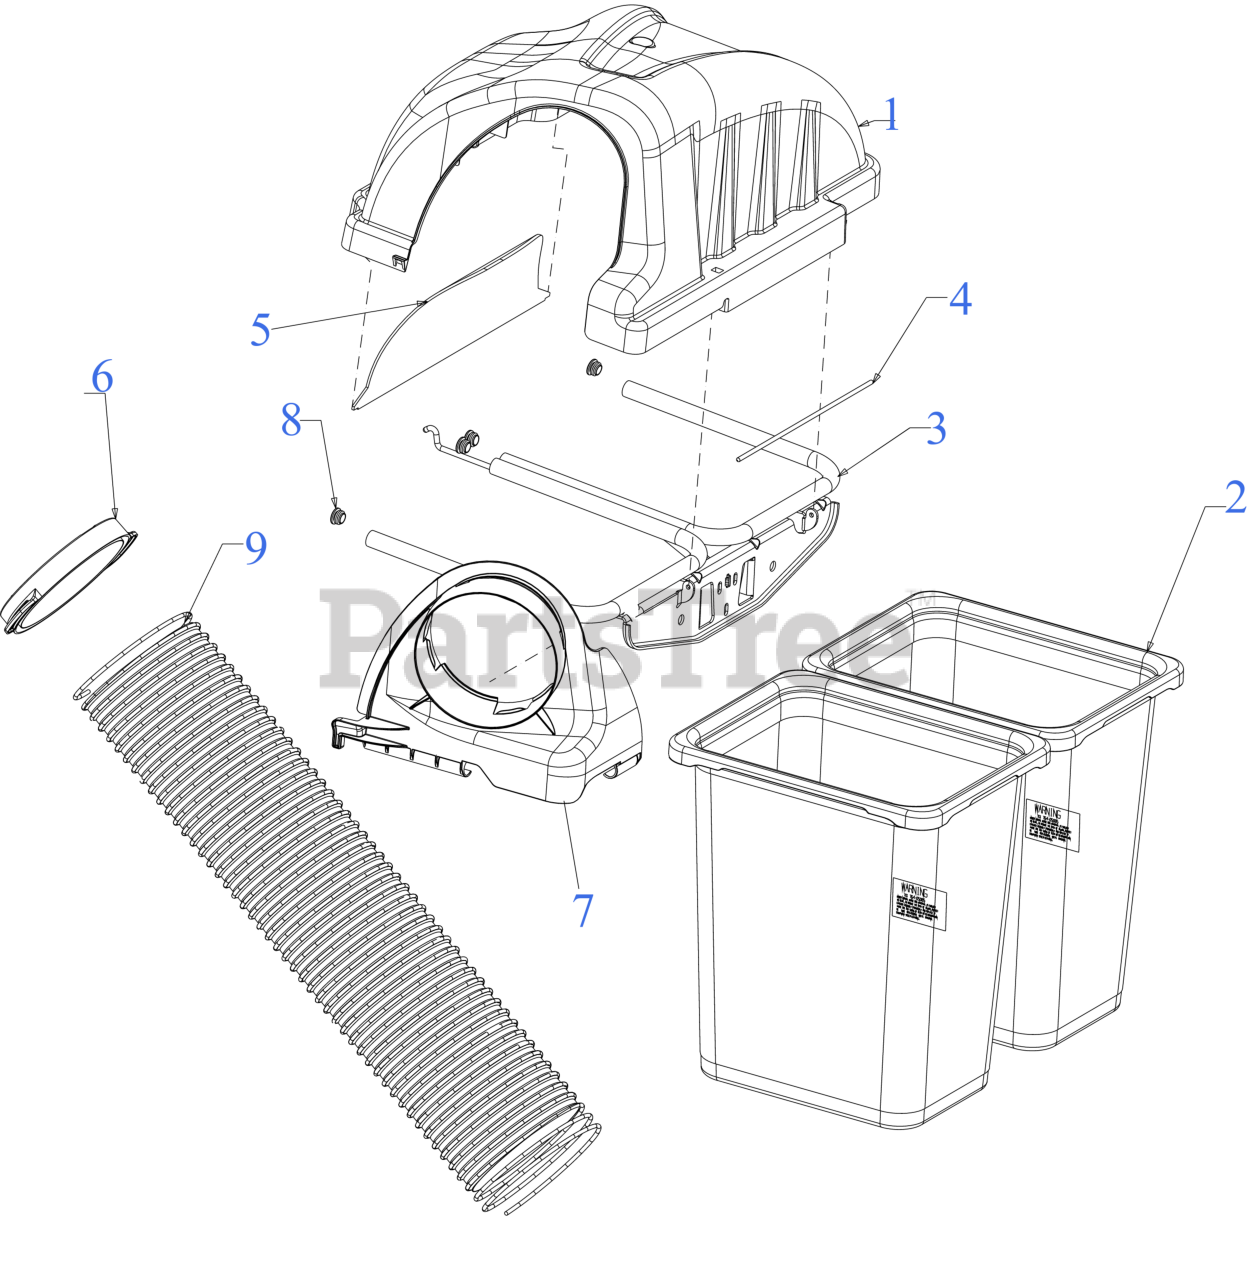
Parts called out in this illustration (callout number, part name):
1	DOUBLE BAGGER COVER
2	GRASSBAG ASSEMBLY W/ HARD BOTTOM (STD)
3	DOUBLE BAGGER SUPPORT
4	PIN 15.10"
5	BAGGER COVER SCREEN
6	BAGGER FLEX HOSE RING
7	UPPER FLEX TUBE SUPPORT
9	BAGGER FLEX HOSE
